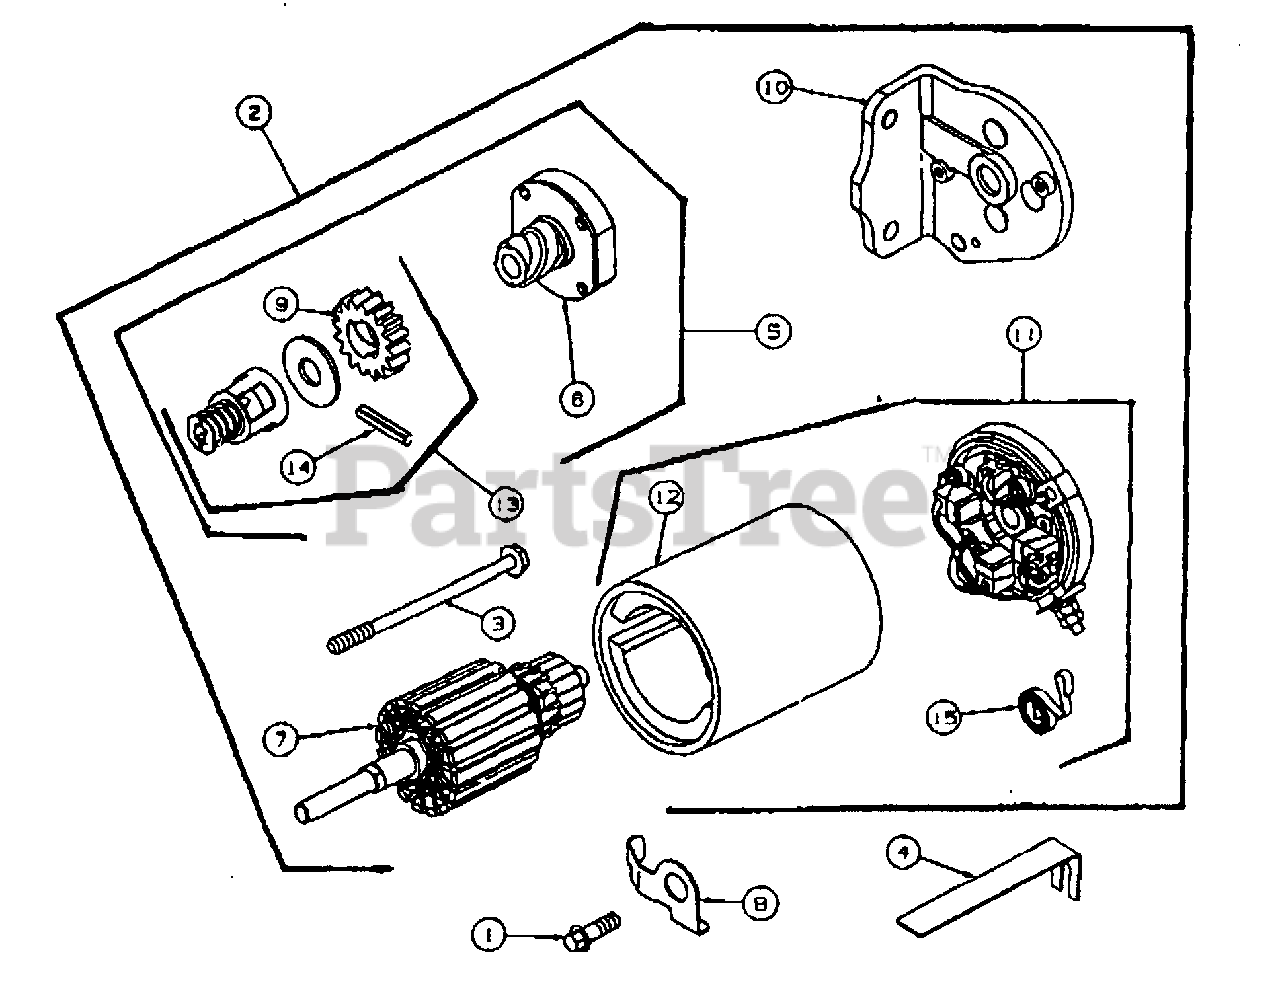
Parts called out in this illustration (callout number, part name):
1	Screw, Hex
2	Starter Assy., Motor
3	Screw, Hex
4	Strap, Starter
5	Starter, Drive Group
6	Clutch Assy
7	Armature Assy
8	Clip, Wire
9	Gear, Starter
10	Drive End Cap Assy
11	Cap Assy, Commutator End
12	Housing Assy
13	Kit, Gear
14	Pin, Roll
15	Spring, Brush
